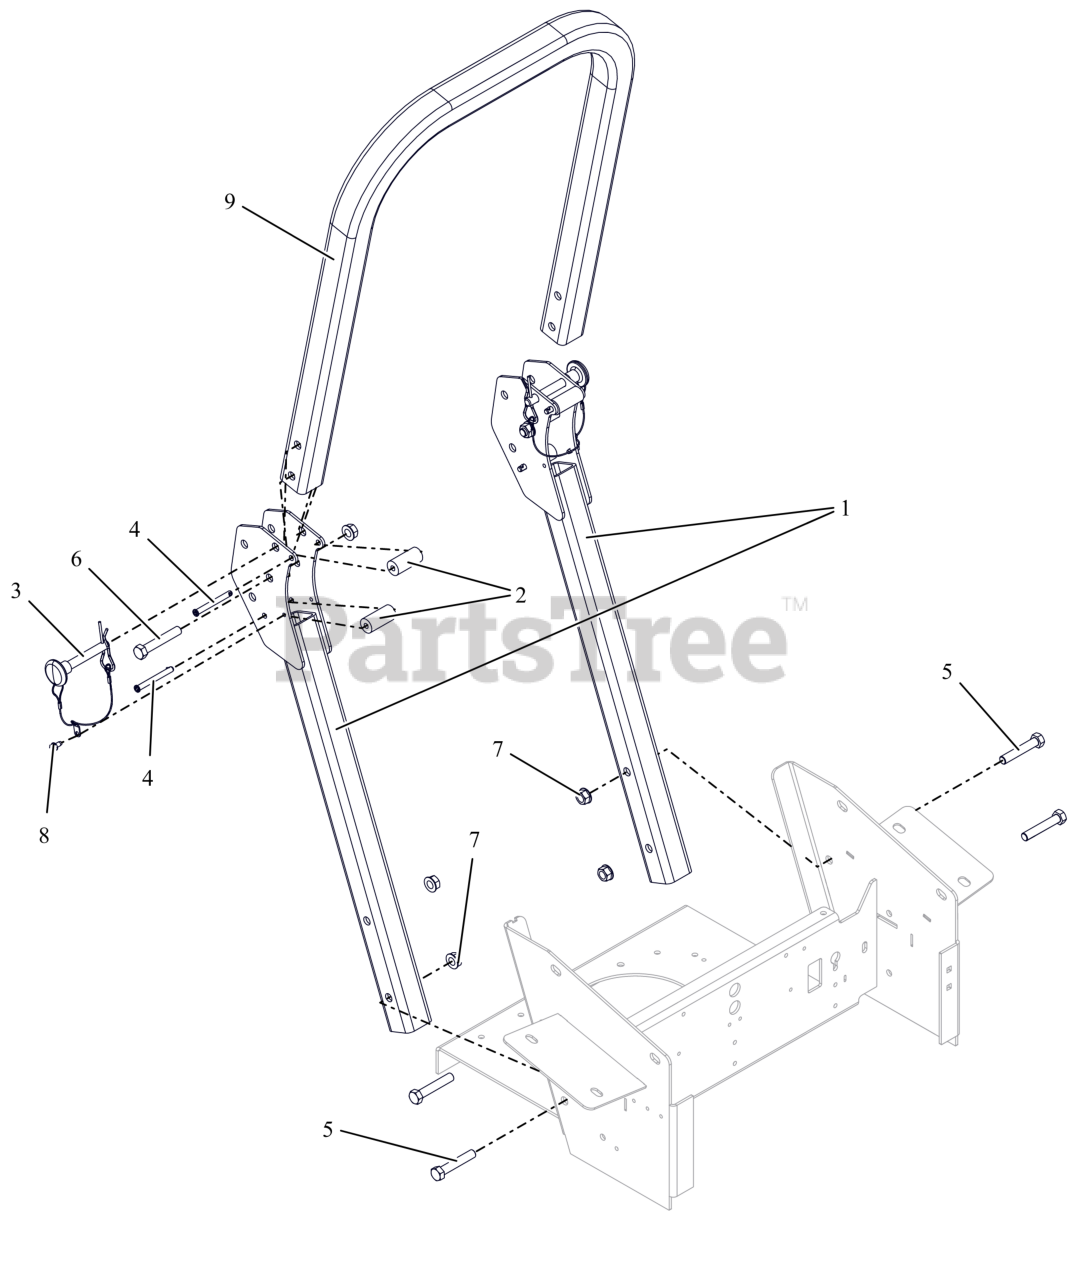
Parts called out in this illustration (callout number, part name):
1	WLDMT, PT/PT100 ROPS MTG POST
2	BUMPER, ROPS ANTI-VIBRATION
3	PIN, ROPS W/LANYARD
4	PIN, SLIC .312 X 2.570
5	BLT,HEX .50-13X2.75 G5 ZCC
6	BLT, HEX .50-13X3.00 G5 ZCC
7	NUT-LK-CTR-FLG .500-13 GG ZCC
8	SCR-TAP .25-20X.50 HWH ZCC
9	HOOP, ROPS
